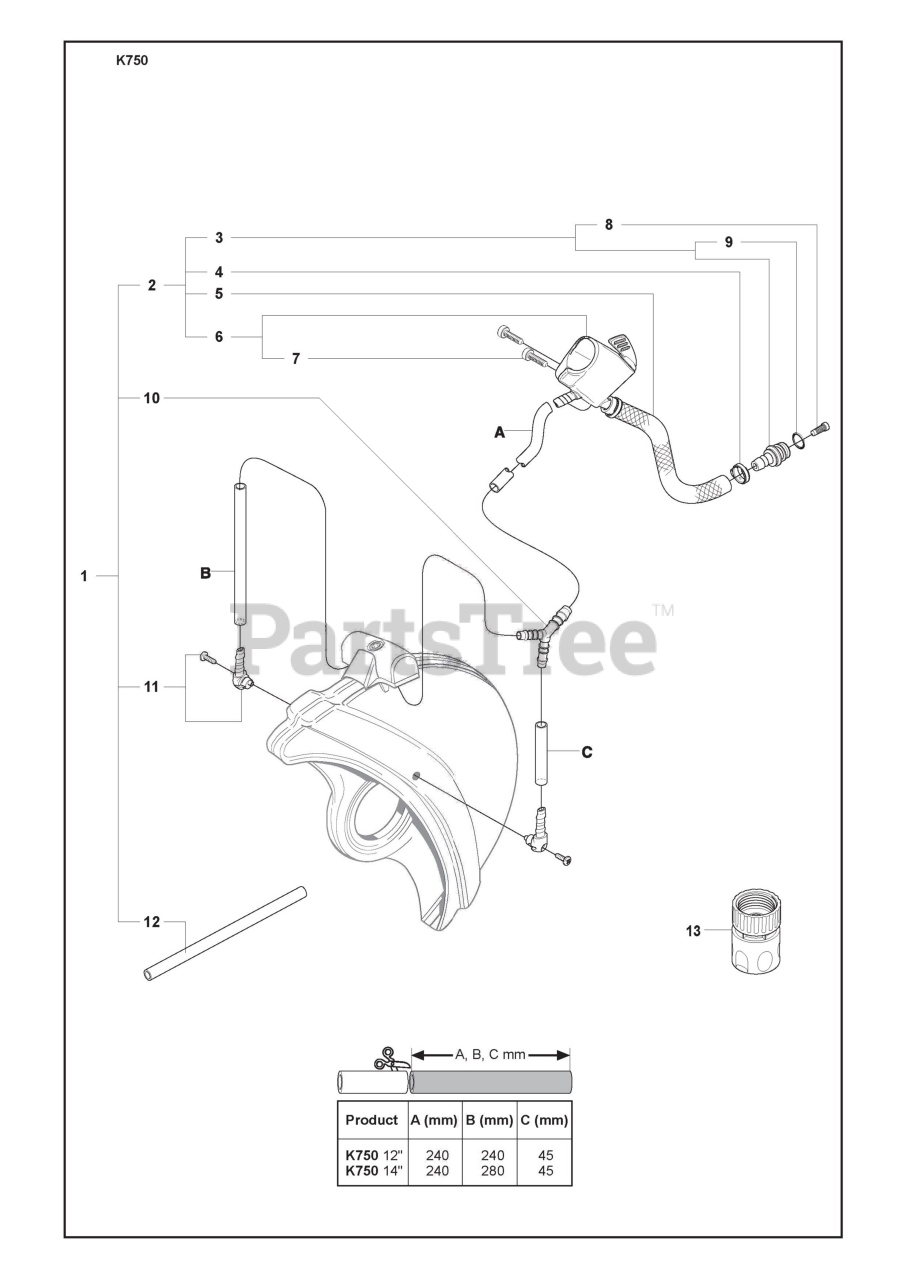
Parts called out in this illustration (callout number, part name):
1	WATER HOSE KIT
2	HOSE
3	NIPPLE
4	HOSE CLAMP
5	HOSE
6	VALVE ASSY
9	O-RING
12	HOSE
13	COUPLER
